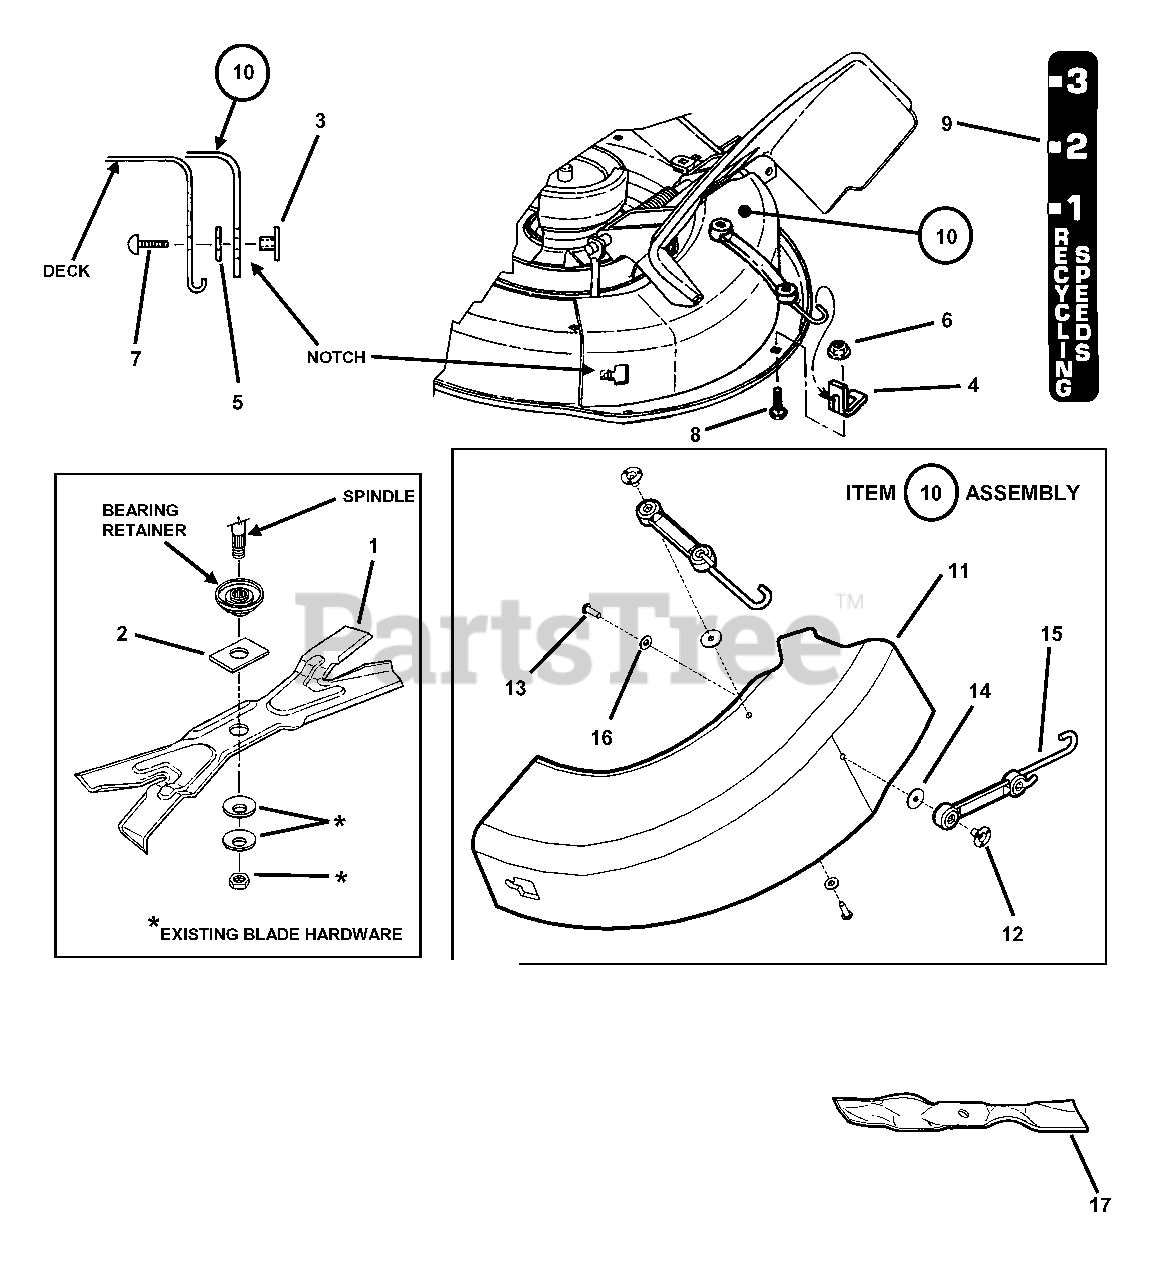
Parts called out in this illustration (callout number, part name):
2	WASHER, Blade
3	TEENUT, 5/16-18
4	BRACKET, Strap Mounting
5	WASHER, 5/16" Flat
6	NUT, 3/8-16 Hex Flange Lock
7	SCREW, 5/16-18 x 5/8" Cross Recess Pan Head Nyloc
8	BOLT, 3/8-16 x 3/4" Square Neck Carriage
9	DECAL, Recycling Ground Speeds
10	ASSEMBLY, Mulching Cover & Strap
11	COVER, Mulching (38" Deck)
12	NUT, #10-24 Weld
13	SCREW, #10-24 Pan Head Cross Recess
14	WASHER, .190 I.D., 3/4" O.D. Flat
15	STRAP, Bag Adapter Mounting
16	WASHER, .219 I.D., 1/2" O.D.
17	BLADE, 19.64" Mulching Wave
